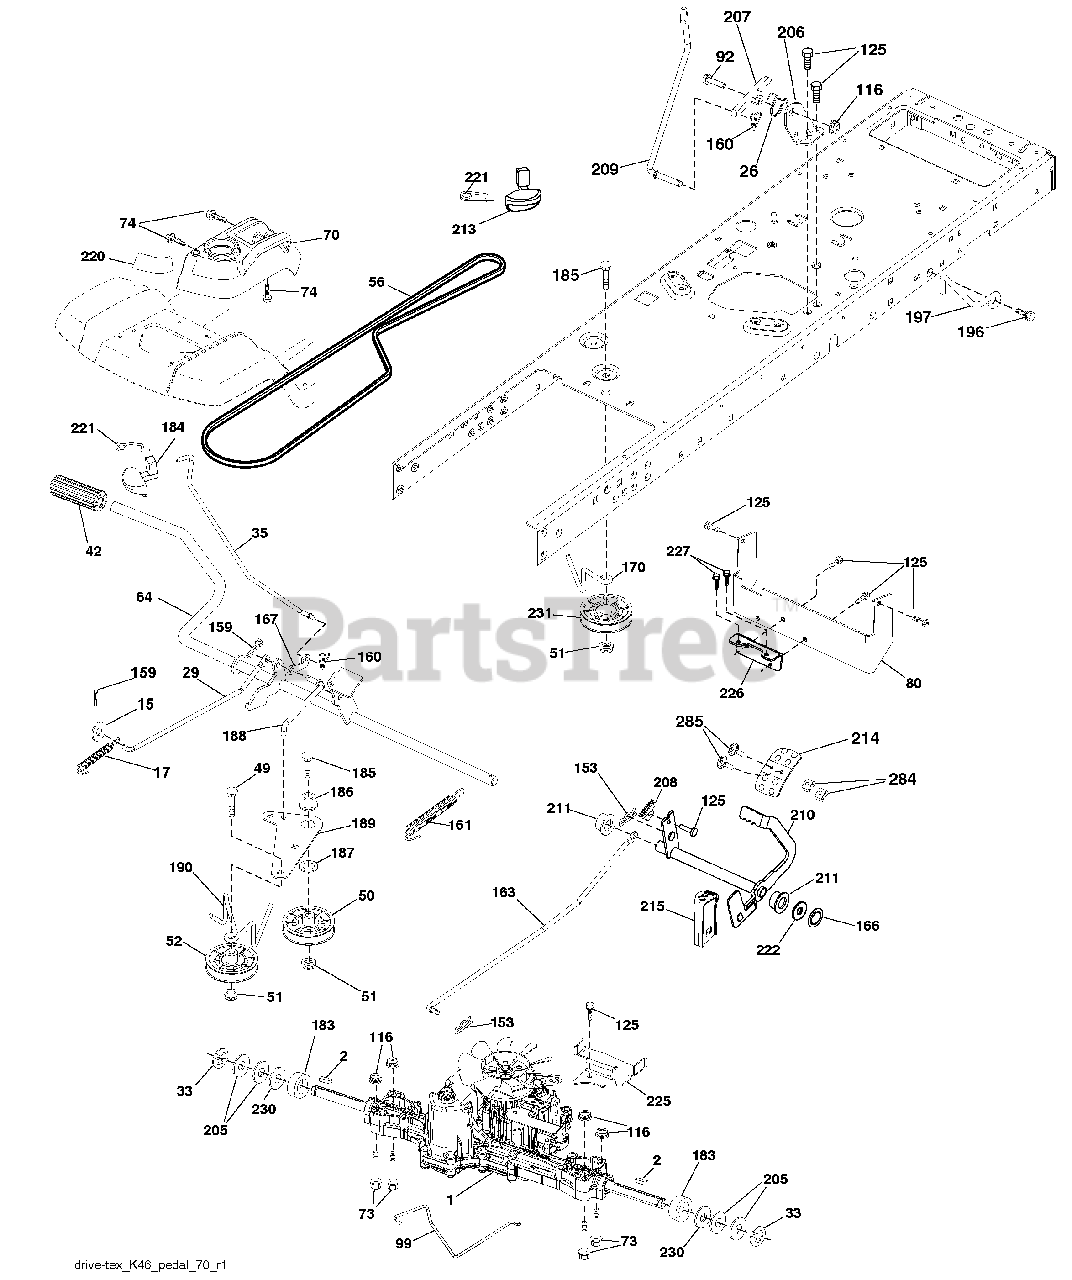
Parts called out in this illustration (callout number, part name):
1	Transaxle, TUFFTORQ K46CR
2	Key
15	Washer 13/32 x 13/16 x 16 Ga.
17	Spring, Brake
26	Spring Return Cruise
29	Rod, Brake
33	Ring E
35	Rod, Brake, Park
42	Cover, Foot Pedal
50	Pulley Idler Flat
51	Lock Nut 3/8-16
52	Idler V-Groove 910" Offset
56	V-Belt, Drive
64	Shaft Asm. Pedal Brake Control
70	Console Asm Pch
73	Bolt Hex Flghd 5/16-18 Gr. 5
74	Screw Hex Wsh Hi-Lo 1/4 x 1/2
80	Bracket Strap Torque
92	Bolt Fin Hex 5/16-18 unc x 1.25
99	Rod Spring Bypass
116	Nut Lock Hex Flange 5/16-18
125	Screw 5/16-18 x 3/4
153	Retainer Spring
159	Pin Cotter 1/8 x 3/4
160	Retainer Clip
161	Spring, Return, Clutch
163	Rod Pedal Control
167	Latch Brake Parking
170	Keeper Belt Centerspan
183	Spacer Split
184	Handle Parking Brake
185	Bolt Rdhd Sqnk 3/8-16 x 2-1/2
186	Spacer Retainer
187	Washer
188	Link Clutch Ground Drive
189	Bellcrank Ground Drive
190	Keeper Bellcrank Ground Drive
196	Screw 3/8-16 x 1
197	Bracket Clutch Anti-Rotation
205	Washer
206	Bracket Mount Latch Cruise
207	Latch Control Cruise
208	Gear Sector Control Cruise
209	Rod Control Cruise
210	Rocker Asm. Pedal Control
211	Bearing Nylon
213	Knob Control Cruise
214	Pedal Forward Husq
215	Pedal Reverse
220	Reflector RH
221	Retainer Spring Clip Handle
222	Washer 21/32 x 1-1/4 x 10 Ga.
225	Keeper Belt Trans.
226	Bracket Mount Torque
227	Screw 5/16-18 x 3/4
230	Washer Hardened
231	Idler V-Groove
284	Nut U-CHNL 1/4-20 550DP .350 PNL
285	Screw PHD 1/4-20 Box Drive
